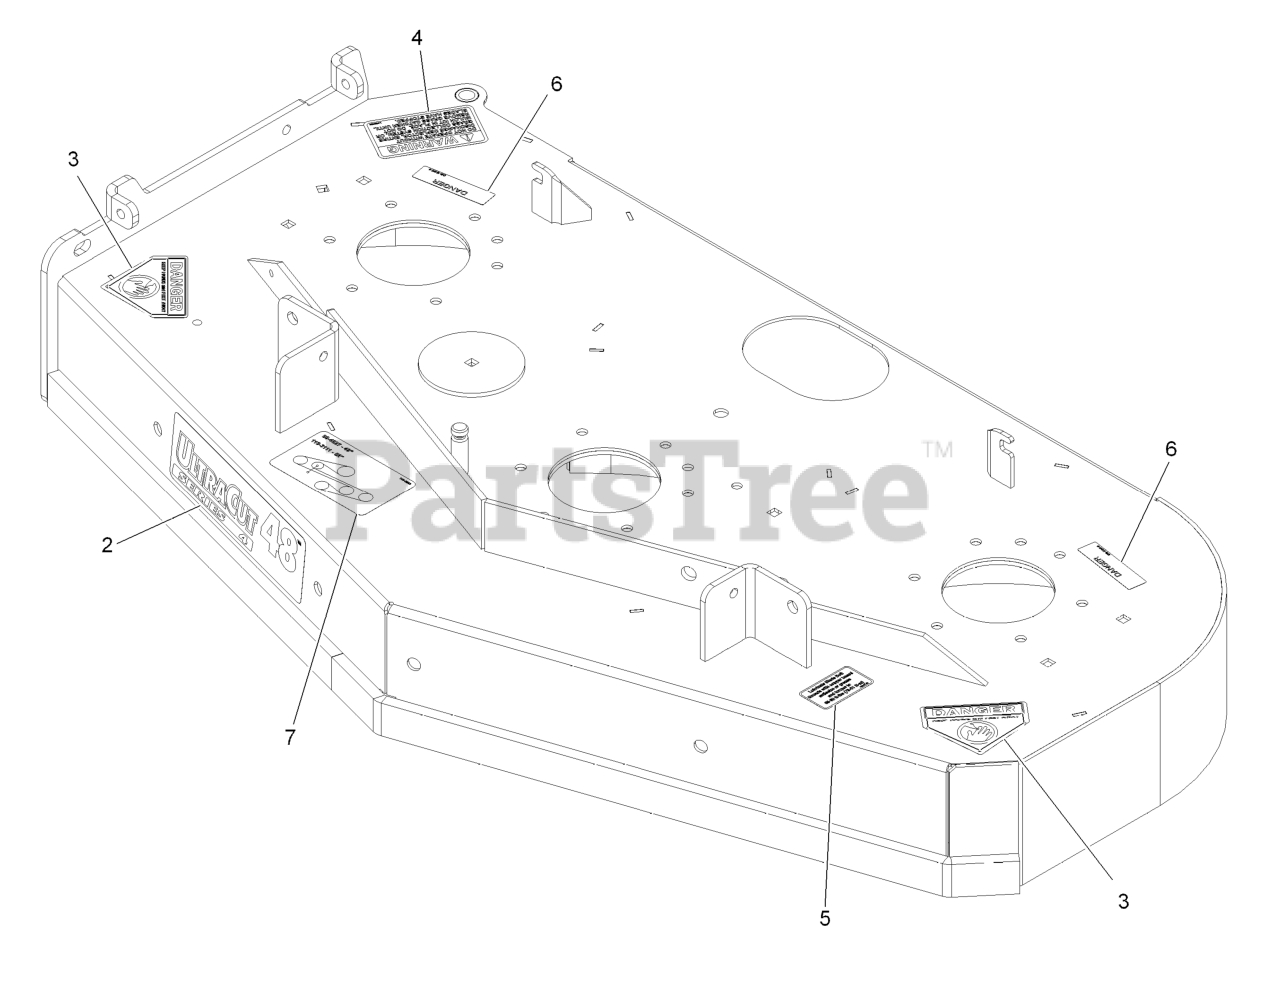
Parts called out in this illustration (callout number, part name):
2	DECAL,ULTRACUT 48 SERIES
3	DECAL-DANGER
4	DECAL-WARNING, DISCHARGE
5	DECAL,BOLT TORQUE
6	DECAL-COVER, MISSING
7	DECAL-BELT ROUTING
